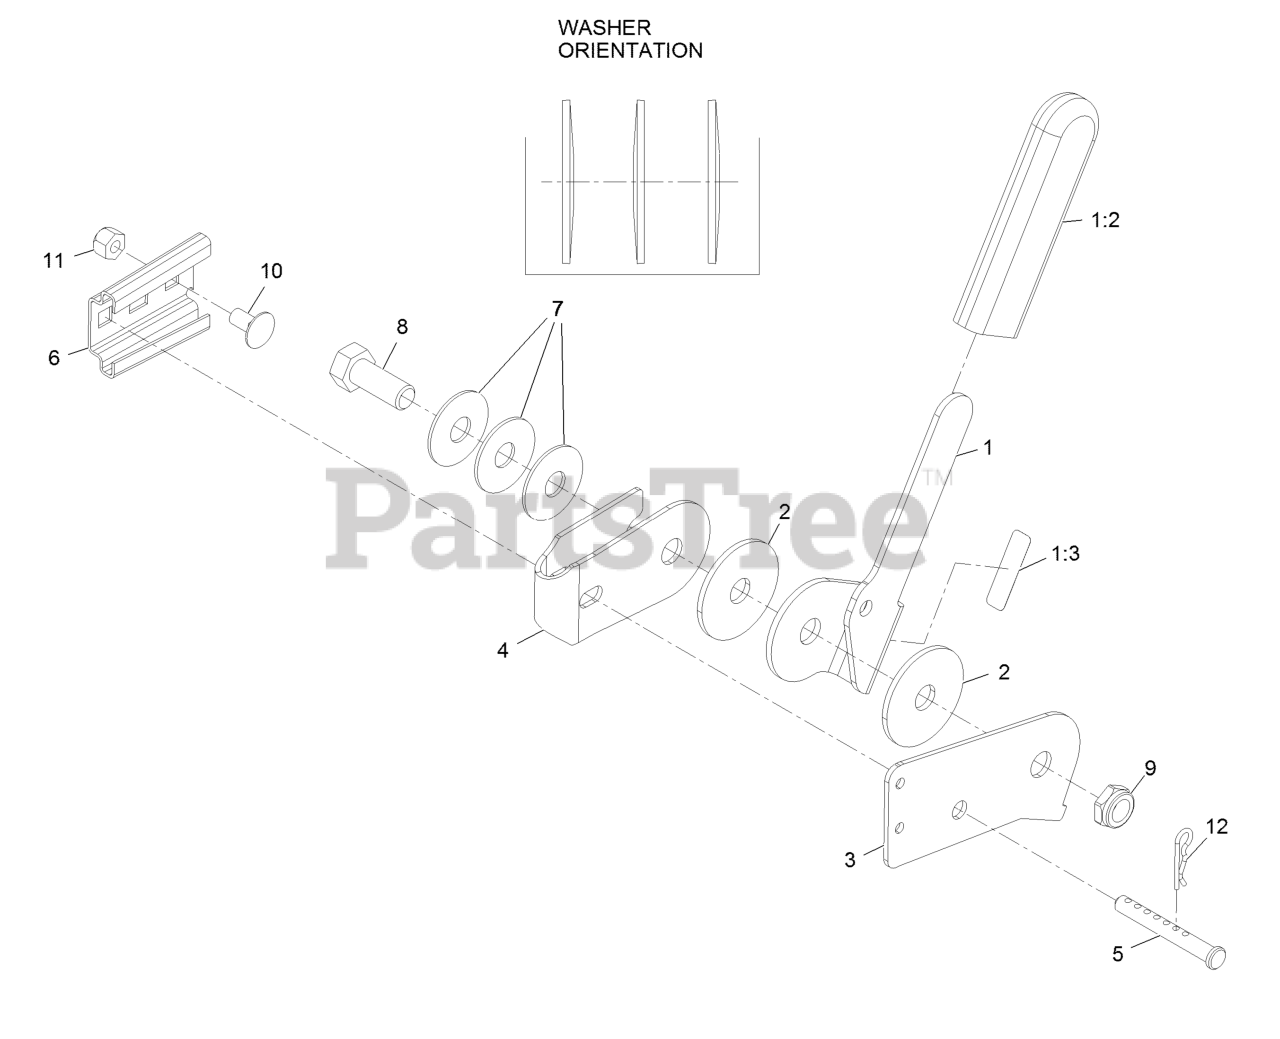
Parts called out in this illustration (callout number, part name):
1	Control Handle ASM-Ocd
1:2	Grip-Lever
1:3	Decal-Operation
2	Disc-Friction
3	Bracket,Control Mount
4	Bracket,Handle Mount
5	Pin-Clevis
6	Bracket-Mounting,Smv
7	Washer-Spring Disc
8	Screw-HH 1/2-13 X 1 1/4
9	Nut-Nyloc 1/2-13 Thin
10	Bolt-Carriage 5/16-18 X 5/8
11	Nut-Nyloc 5/16-18
12	Hairpin-Cotter
